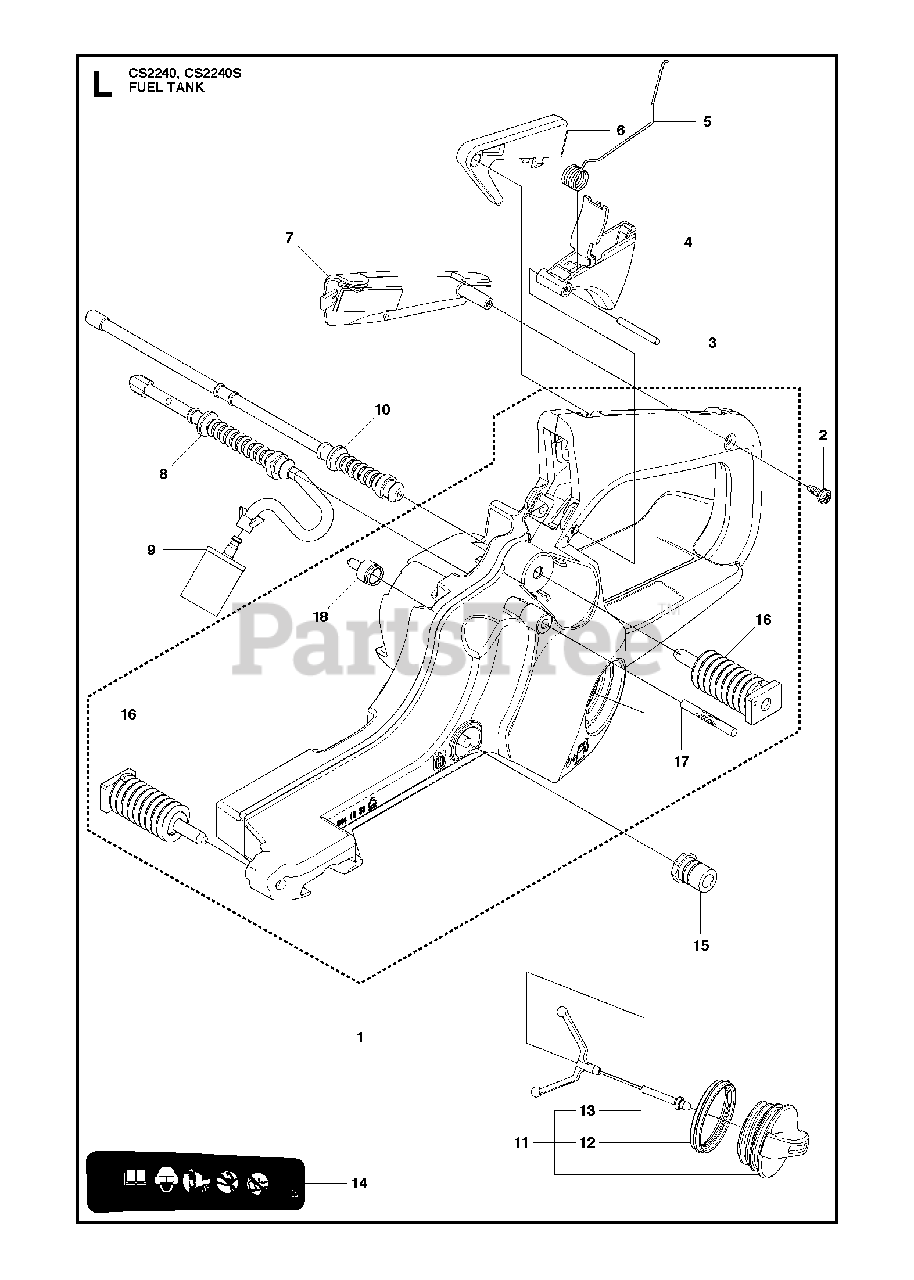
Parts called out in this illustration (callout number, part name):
4	THROTTLE CONTROL
6	THROTTLE LOCKOUT
7	HANDLE INSERT
8	RP FUEL HOSE
9	FUEL FILTER
10	RP RETURN HOSE
11	TANK CAP ASSY
12	SEALING
13	HOLDER
15	LATERAL SUPPORT
16	ANTIVIBRATION ELEMENT
17	GROOVED PIN
18	FUEL TANK VENT
